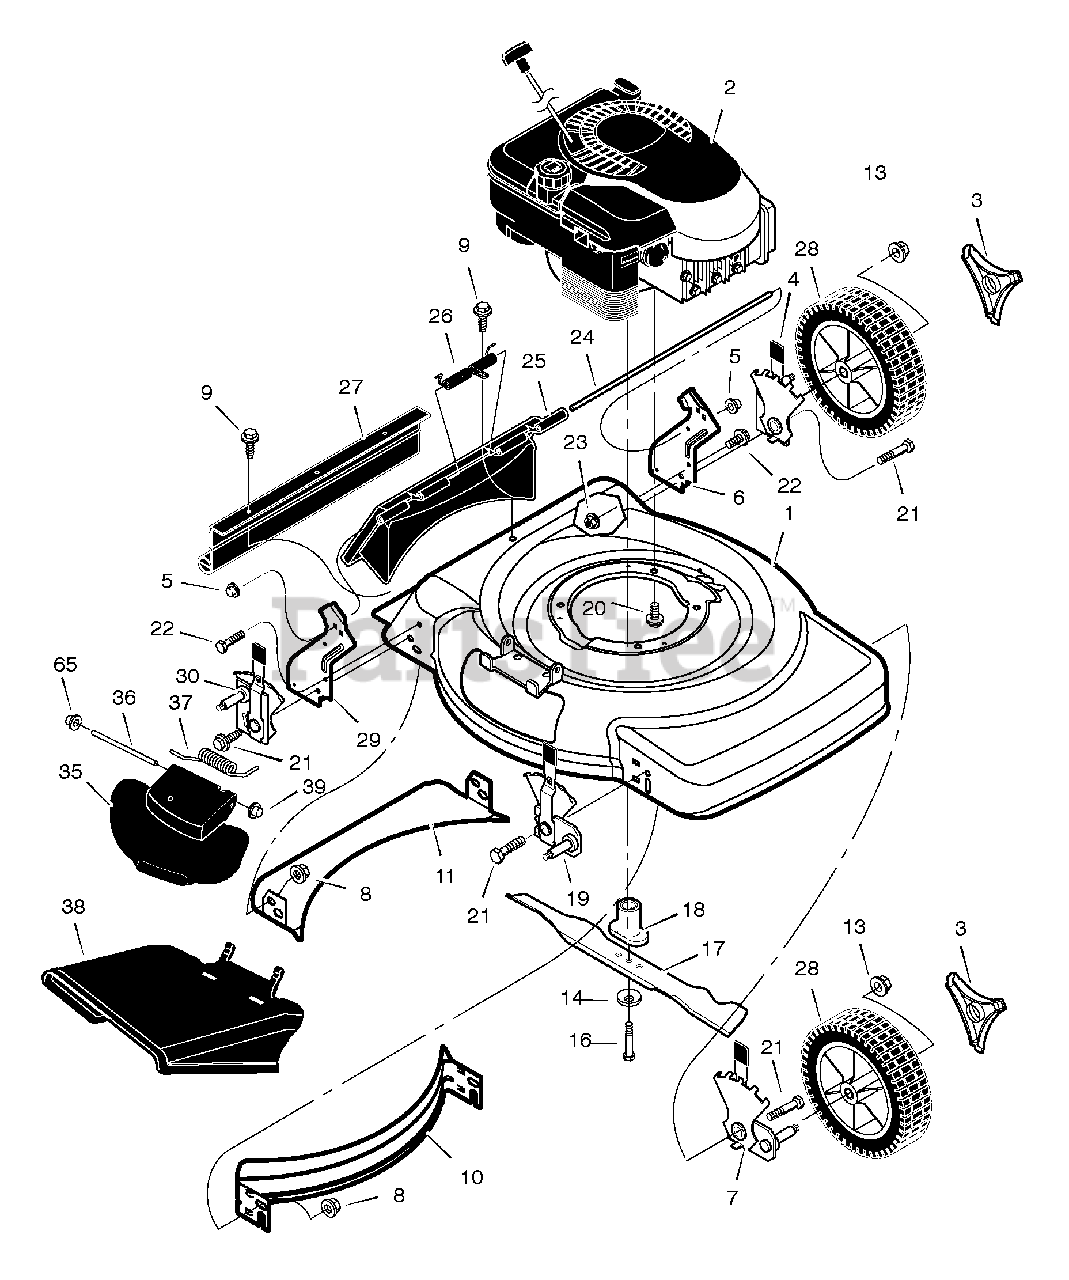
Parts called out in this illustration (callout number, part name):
2	Engine *
3	Cap, Hub
4	Adjuster, Left Rear Height
5	Push Retainer
6	Bracket, Left Handle
7	Adjuster, Left Front Height
8	Nut, Flange
9	Screw
10	Baffle, Front
11	Baffle, Rear
13	Nut, Flange
14	Washer, Belleville
17	Blade
18	Adapter, Blade
19	Adjuster, Right Front Height
20	Bolt, Engine
21	Bolt
22	Bolt
23	Nut, Flange
24	Rod, Pivot
25	Door, Rear (Black)
26	Spring
27	Guard, Rear
28	Wheel & Tire
29	Bracket, Right Handle
30	Adjuster, Right Rear Height
35	Cover, Mulch (Black)
36	Rod, Pivot
37	Spring, Torsion
38	Deflector, Chute (Black)
39	Push On Cap
